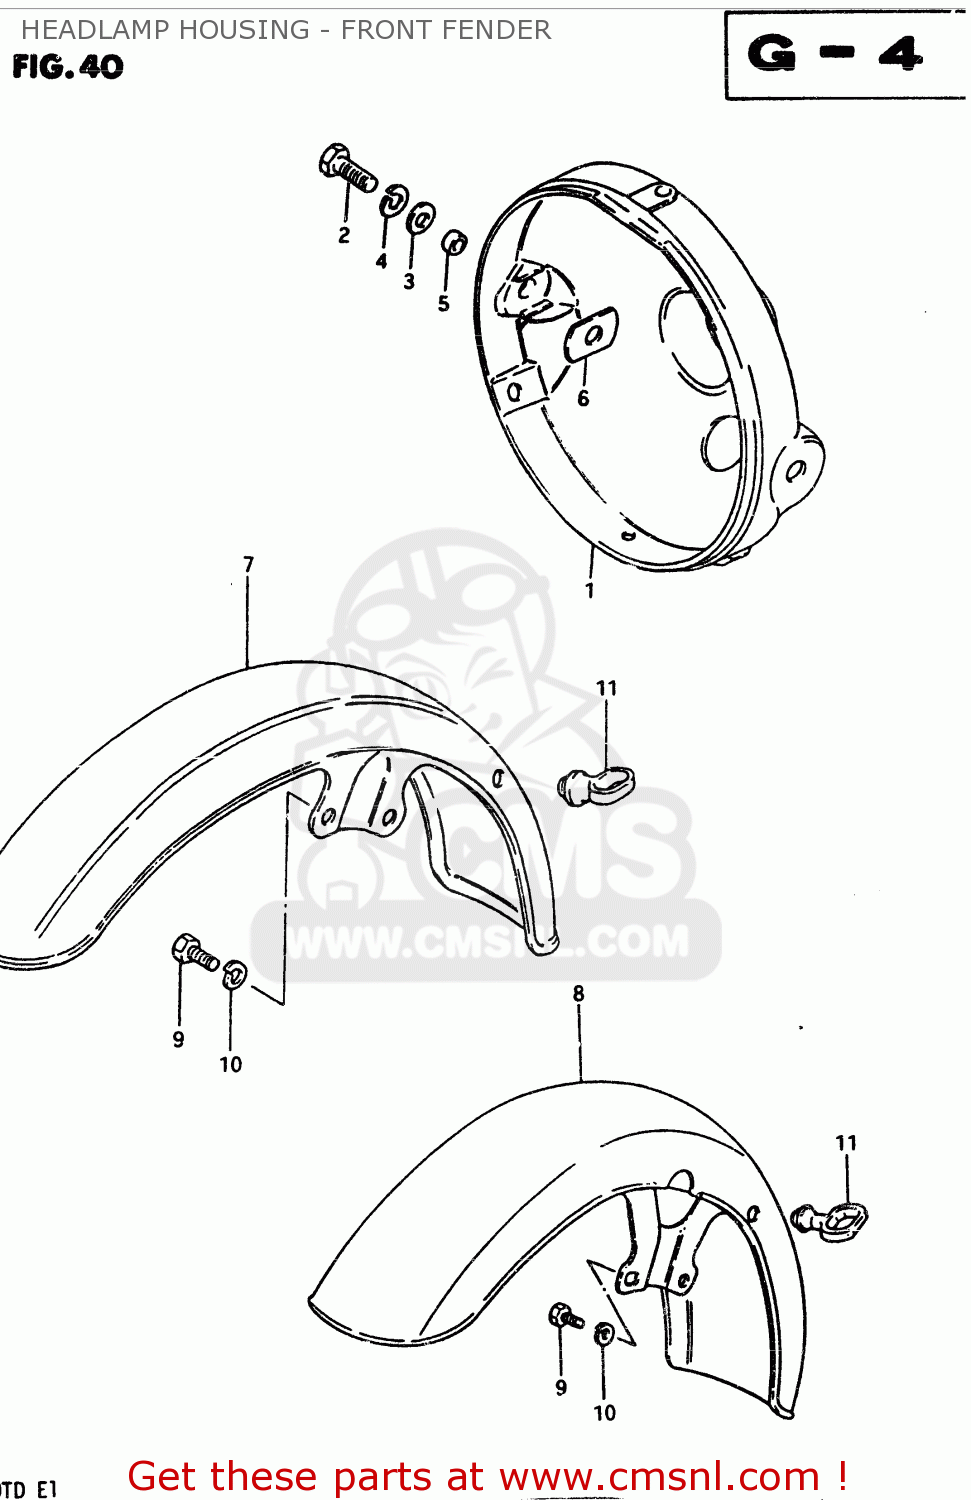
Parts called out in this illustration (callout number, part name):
1	HOUSING,HEADLAMP
2	BOLT
3	WASHER
4	WASHER
5	SPACER (8.8X12X7)
6	CUSHION
7	FENDER,FR
8	FENDER,FRONT
9	BOLT
10	LOCK WASHER
11	GUIDE,CABLE
